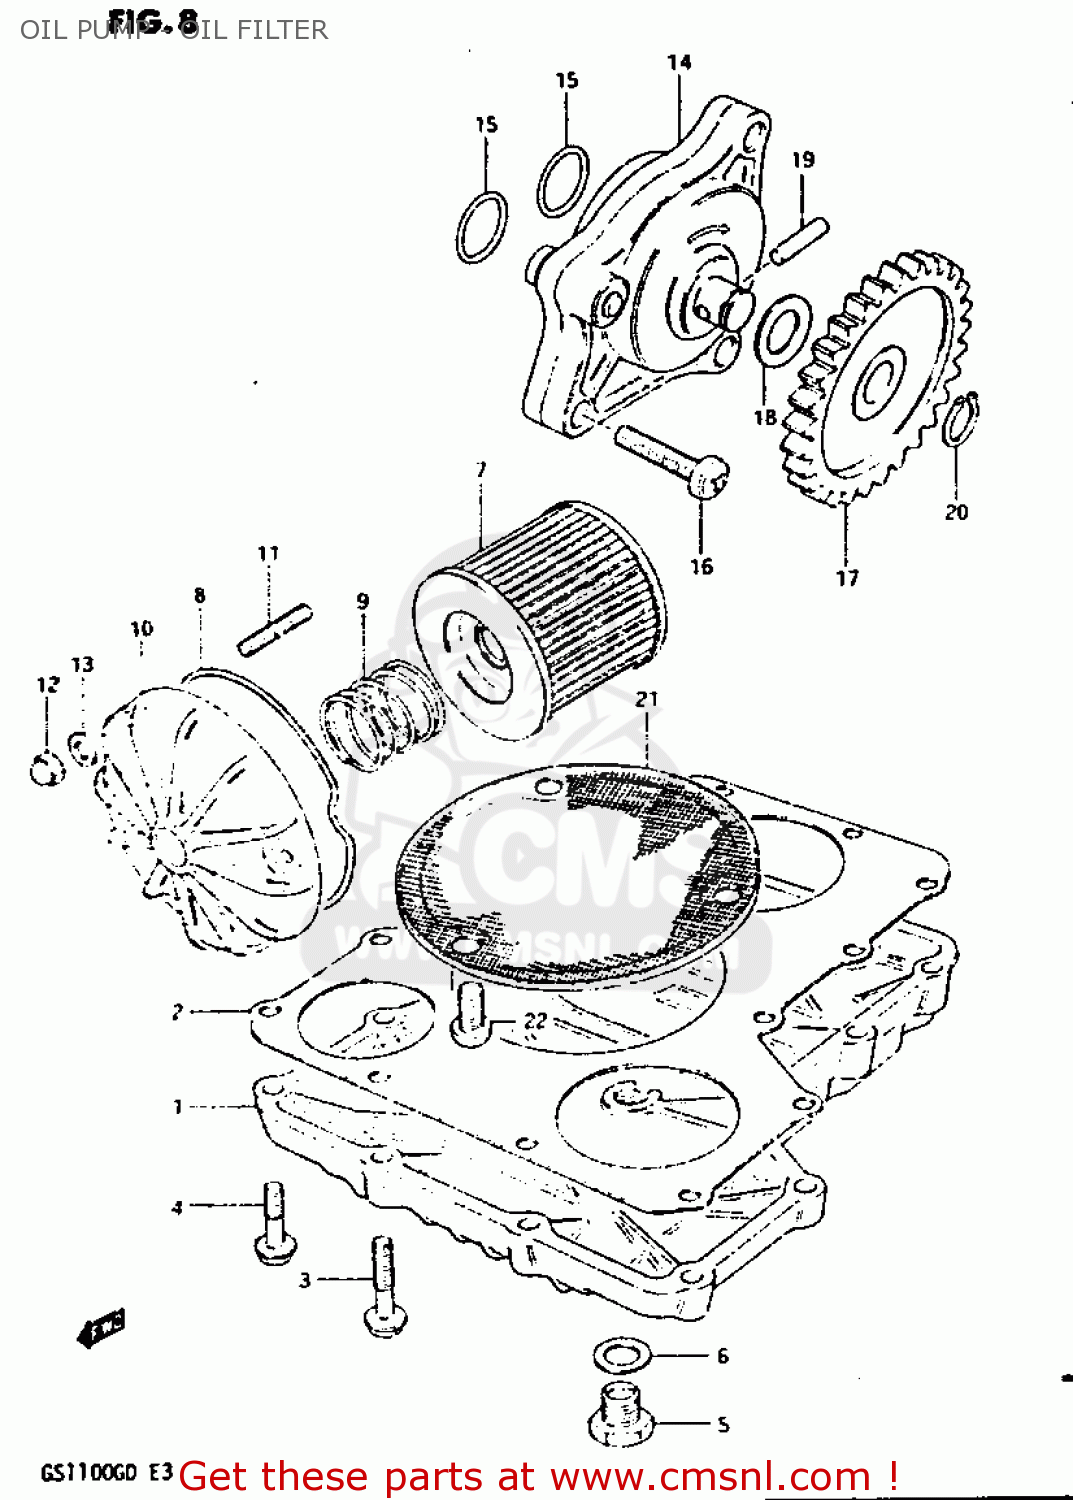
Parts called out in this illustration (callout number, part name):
1	PAN,OIL
2	GASKET,OIL PAN (NAS)
3	BOLT
4	BOLT
5	PLUG
6	GASKET(14X19.2X2) (NAS)
7	FILTER ASSY,ENGINE OIL
8	O RING,OIL FILTER CHAMBER CAP
9	SPRING
10	CAP,OIL FILTER
11	STUD 6X20
12	NUT
13	WASHER
14	PUMP ASSEMBLY,ENGINE OIL
15	O RING(D:1.9,ID:13)
16	SCREW
17	GEAR,ENG OIL PUMP DRIVEN(NT:33
18	SHIM
19	PIN(4X15.8)
20	CIRCLIP
21	STRAINER,ENGINE OIL
22	SCREW 6X12
